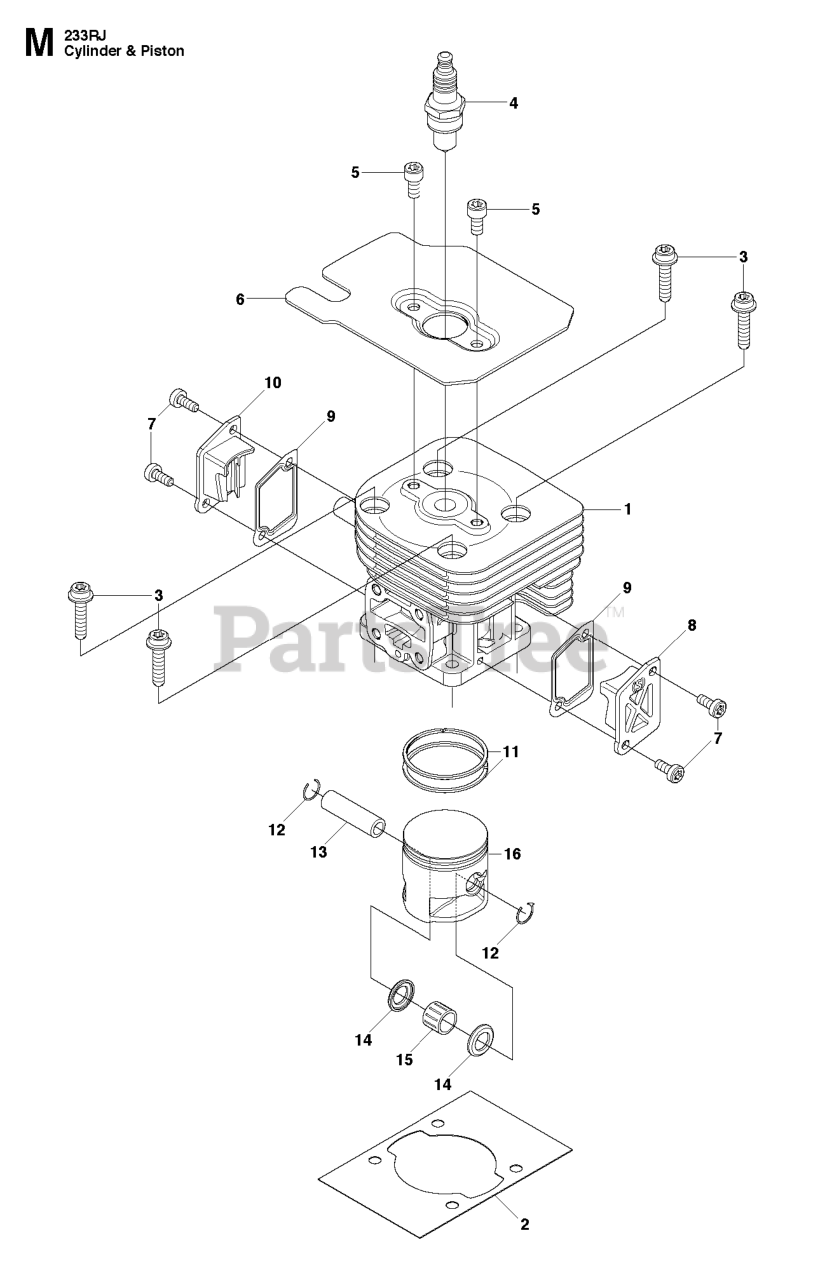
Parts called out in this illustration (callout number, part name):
2	GASKET
3	BOLT TORX
4	SPARK PLUG NGK CMR7H
5	BOLT TORX M5XL10 T27
7	SCREW
8	COVER, TRS
9	GASKET, TR
10	COVER,TRF (RPLS 848F6012D1)
11	RING
12	RING, SNAP
13	PIN
14	WASHER (RPLS 331041341)
15	BEARING
